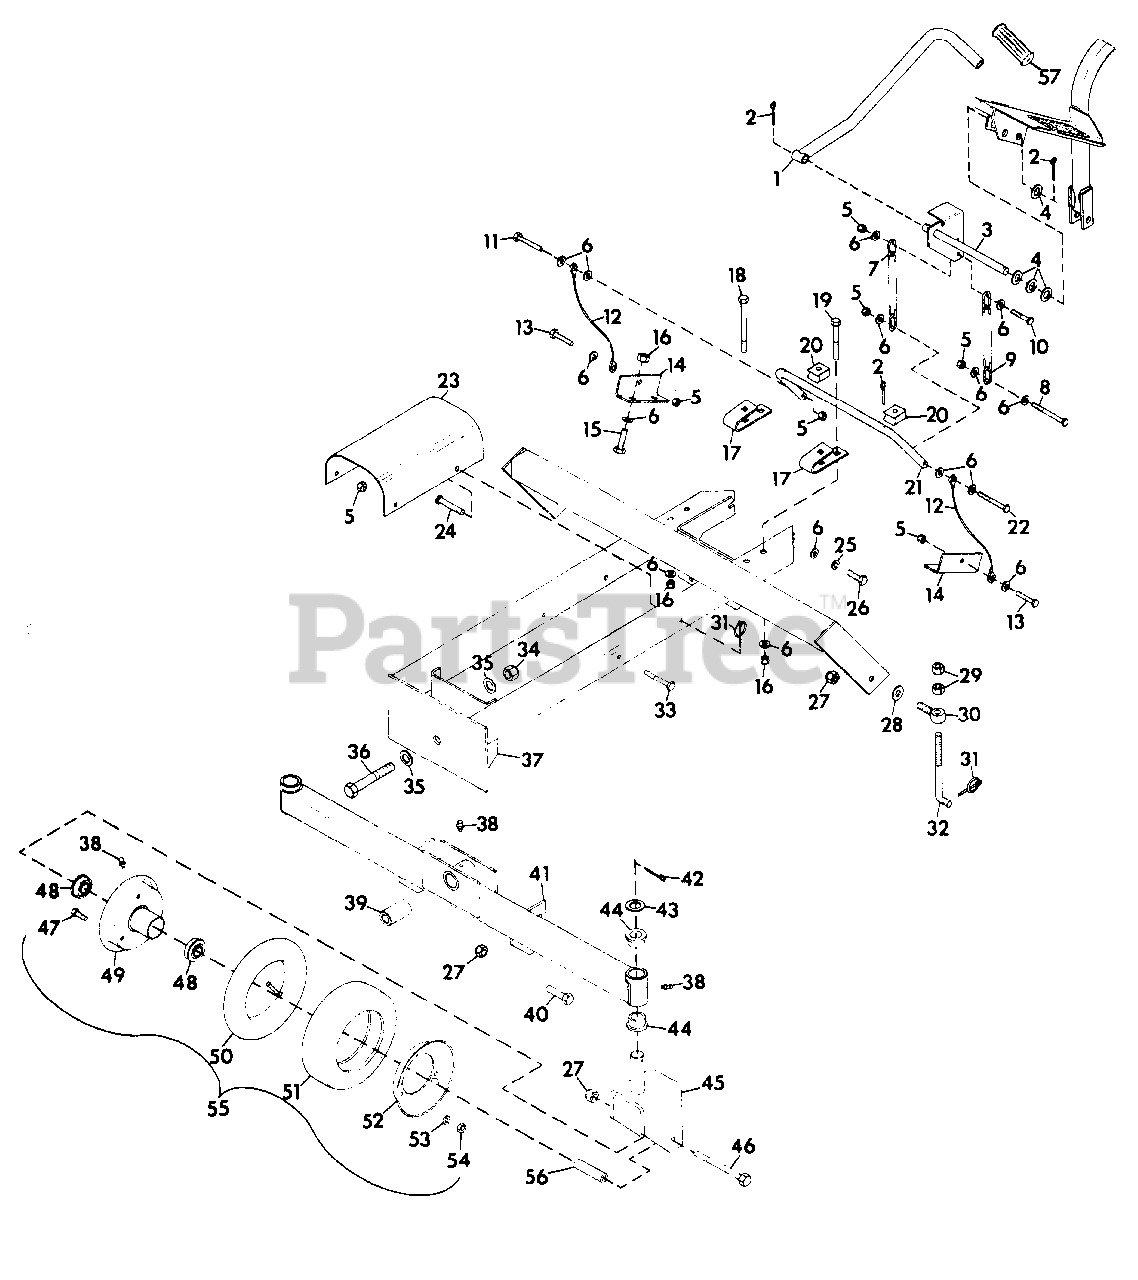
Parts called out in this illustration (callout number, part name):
1	WELDMENT, LIFT LEVER
2	PIN, COTTER .12X1.25
3	WELDMENT, LIFT BRACKET
4	WASHER, FLAT .656X1.250X.100
5	NUT, LOCK 5/16-18
6	WASHER, FLAT .406X.812X.065
7	CHAIN, LIFT(8 LINKS)
8	BOLT, HEX 5/16-18X3.25
9	CHAIN, LIFT(7 LINKS)
10	BOLT, HEX 5/16-18X1.25
11	BOLT, HEX 5/16-18X1.75
12	CABLE, LIFT
13	BOLT, HEX 5/16-18X1.00
14	BRACKET, LIFT
15	BOLT, HEX 3/8-16X1.00
16	NUT, LOCK 3/8-16
17	BRACKET, AXLE SUPPORT
18	BOLT, HEX 3/8-16X4.00
19	BOLT, HEX 3/8-16X3.00
20	STOP, NYLON
21	ARM, PIVOT
22	BOLT, HEX 5/16-18X2.00
23	GUARD, PTO SHAFT
24	PIN, CLEVIS
25	WASHER, LOCK 3/8
26	BOLT, HEX 3/8-16X1.38
27	NUT, LOCK 1/2-13
28	WASHER, FLAT .500X1.250X.083
29	NUT, JAM 1/2-13 HEX
30	BOLT, EYE
31	PIN, KLIK
32	ROD, HEIGHT ADJUSTMENT
33	BOLT, HEX 5/16-18X2.50
34	NUT, LOCK 3/4-10
35	WASHER, FLAT .812X1.469X.130
36	BOLT, HEX 3/4-10X4.50
37	WELDMENT, MOWER FRAME
38	FITTING, LUBE 1/4-28
39	TUBE, PIVOT
40	BOLT, HEX 1/2-13X1.375
41	AXLE
42	PIN, COTTER .187X1.625
43	RACE, BEARING THRUST
44	BUSHING, PIVOT
45	WELDMENT, CASTER FORK
46	BOLT, HEX 1/2-13X5.00
47	BOLT, HEX 3/8-24X.75
48	BEARING, GAUGE WHEEL
49	WHEEL, HALF WITH TUBE
50	TUBE, INNER
51	TIRE, GAUGE WHEEL
52	WHEEL, HALF PLAIN
53	WASHER, LOCK 3/8 SP HEAVY
54	NUT, HEX 3/8-24
55	WHEEL, GAUGE
56	BUSHING, WHEEL
57	GRIP
